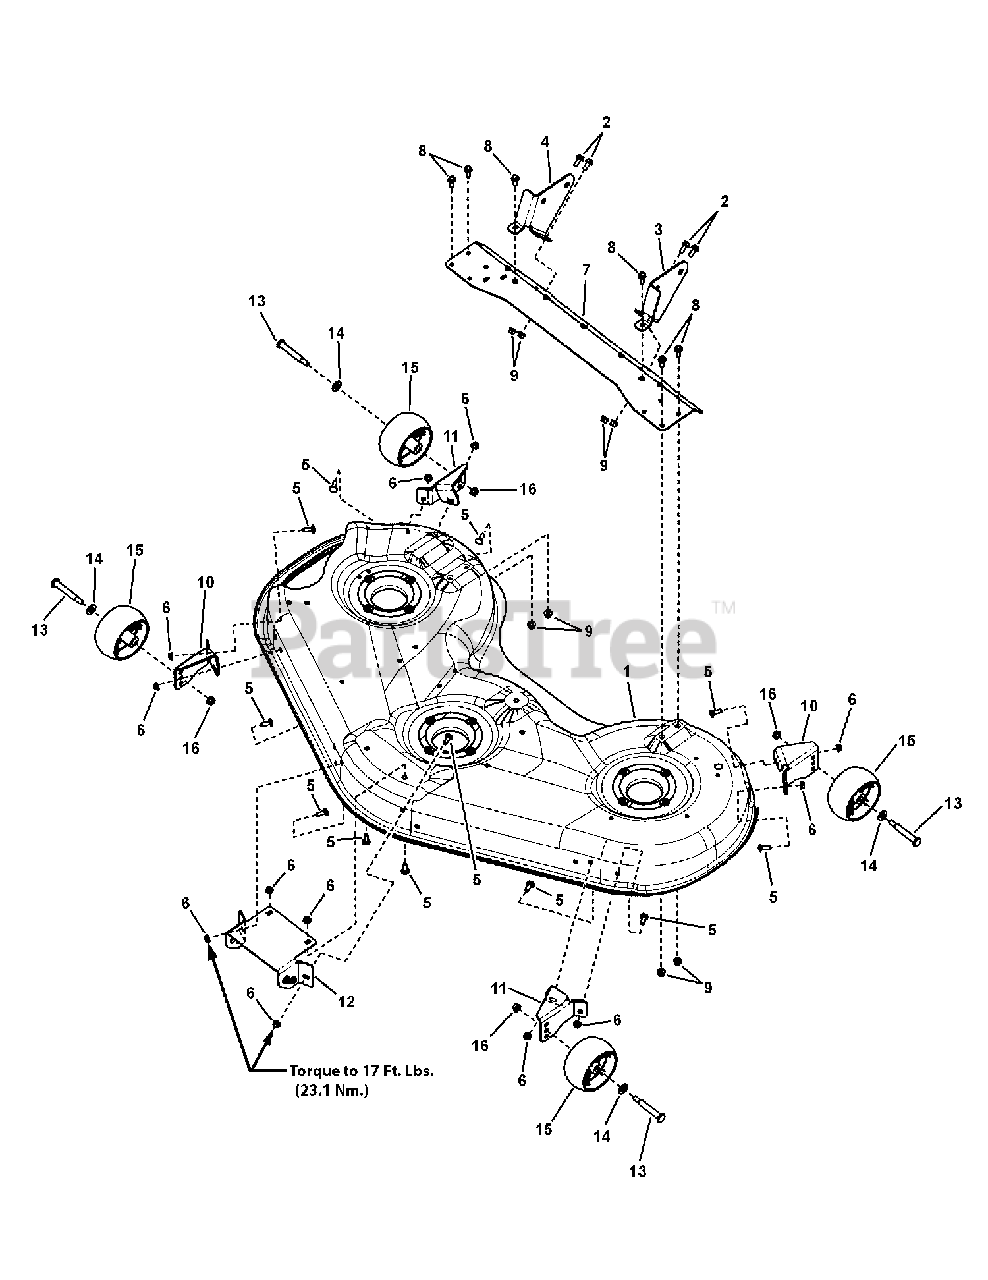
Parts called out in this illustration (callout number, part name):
1	HOUSING, 52" Mower (Orange)
1	HOUSING, 52" Mower (Red)
2	SCREW, 5/16-18 x 3/4" Hex Flange Lock, Black
3	BRACKET, LH Rear 46/52 ZTR - Black
4	BRACKET, RH Rear 46/52 ZTR - Black
5	BOLT, 5/16-18 x 7/8" Round Head Short Square Neck, GR 5, Black
6	NUT, 5/16-18 Hex Flange Lock, Small - Black
7	SUPPORT, Rear Cross
8	SCREW, 5/16-18 x 1" Hex Washer Head Self-Tap, Black
9	NUT, 5/16-18 Hex Flange Nyloc
10	BRACKET, Gauge Wheel, LH
11	BRACKET, Gauge Wheel, RH
12	HITCH, Front, 46/52 Mower
13	SHOULDER BOLT, 3/8-16 x 3.41" .750 Thread Yellow
14	WASHER, 1/2" Flat (0.51 ID x 1.00 OD x .10 Thick) Black
15	GAUGE WHEEL, Black Poly 5" Dia.
16	NUT, 3/8-16 Hex Flange Esna, Black
